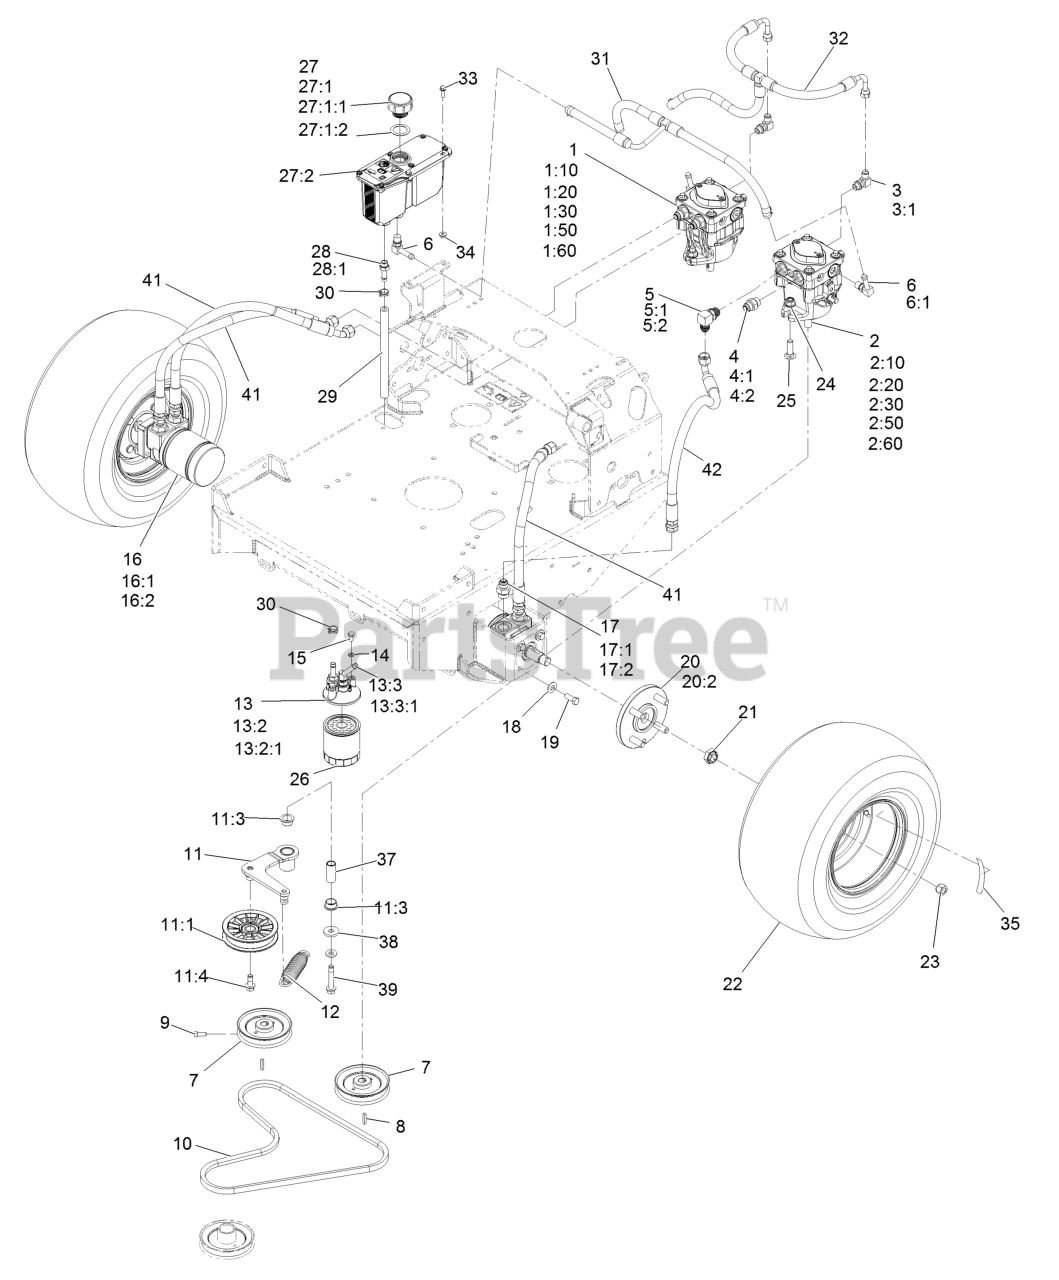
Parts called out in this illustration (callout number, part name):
1	PUMP-HYD PE RH TTH
1:10	INPUT SHAFT KIT
1:20	BEARING-THRUST
1:30	CYLINDER BLOCK KIT
1:50	SEAL OVERHAUL KIT
1:60	KIT, 10CC PUMP KIT
2	PUMP-HYD PE LH TTH
2:10	INPUT SHAFT KIT
2:20	BEARING-THRUST
2:30	CYLINDER BLOCK KIT
2:50	SEAL OVERHAUL KIT
2:60	KIT, 10CC PUMP KIT
3	FITTING-ELBOW, 90 DEG
3:1	O-RING
4	FITTING-STRAIGHT
5	FITTING-90 DEG
6	FITTING-ELBOW, 90
6:1	O-RING
7	SHEAVE ASM
9	SCREW-SET, SQH
10	BELT
11	ASM, PUMP IDLER
11:1	PULLEY-IDLER, FLAT
11:3	BUSHING-FLANGE
11:4	SCREW-HFH
12	SPRING-EXTENSION
13	ASM, FILTER HEAD
13:2	ADAPTER-STRAIGHT
13:2:1	O-RING
13:3	FITTING-BARBED, 45 DEG
13:3:1	O-RING
14	WASHER-LOCK
15	SCREW-HH
16	HYD MOTOR ASM
16:1	SEAL KIT
16:2	BEARING AND SEAL KIT
17	FITTING-STRAIGHT
17:1	O-RING
18	WASHER-BELLEVILLE
19	SCREW-HH
20	WHEEL HUB ASM
20:2	STUD-WHEEL
21	NUT-LOCK
22	ASM, DRIVE TIRE
23	NUT-LUG
24	NUT-HF, NI
25	SCREW-HH
26	FILTER-25 MICRON, BI-DIRE
27:1	Reservoir-HYD
27:1:1	Cap-Reservoir, HYD
27:1:2	GASKET-CAP
27:2	DECAL-WARNING
28	ADAPTER-STRAIGHT
28:1	O-RING
29	HOSE-CHARGE
30	CLAMP-HOSE
31	HOSE, CASE
32	HOSE, CHARGE
33	SCREW-HWH
35	DECAL-TORQUE WHEEL LUG-HU
37	PIVOT, IDLER
39	SCREW-HHF W/ PATCH
41	HOSE,HYDRAULIC W/COVER
42	HYD HOSE ASM
